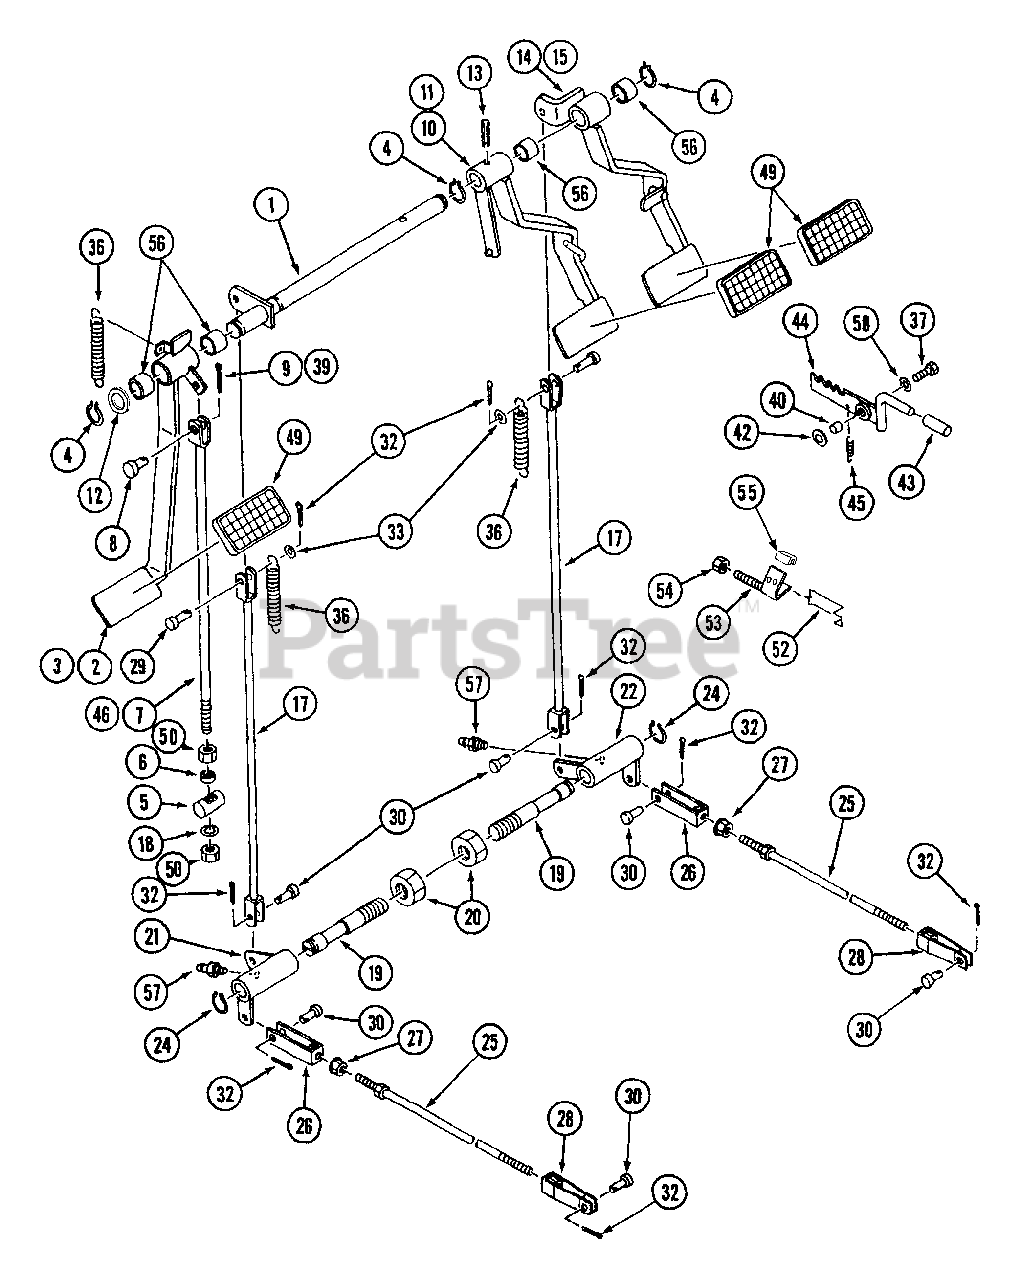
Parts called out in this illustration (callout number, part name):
2	Pedal, Clutch PTO
3	Pedal, Clutch
7	Rod, Clutch
8	Pin, Clevis
9	Pin, Split
10	Pedal, Brake L.H.
11	Pedal, Brake L.H.
14	Pedal, Brake R.H.
15	Pedal, Brake R.H.
21	Link, Brake L.H.
22	Link, Brake R.H.
27	Nut
42	Liner t=0.4
44	Lever, Parking
52	Hook, Clutch Pedal
53	Bolt, Stopper
55	Rubber Edge
57	Nipple, Grease
